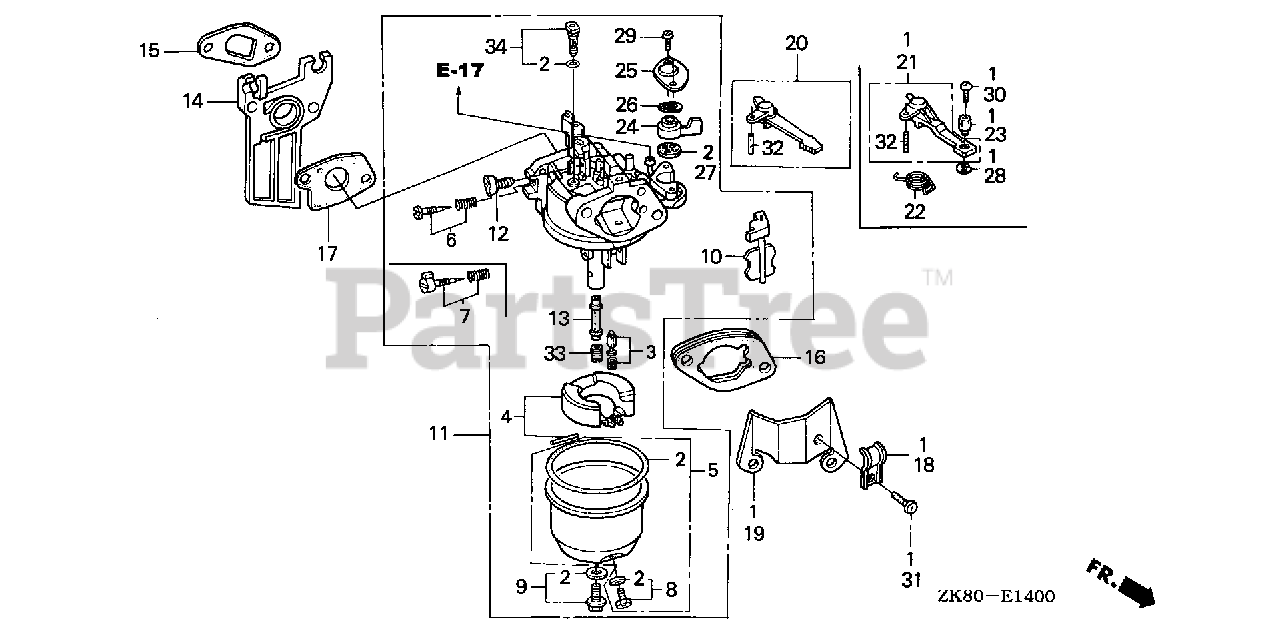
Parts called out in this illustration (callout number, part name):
1	CHOKE KIT, REMOTE CONTROL
2	GASKET SET
3	VALVE SET, FLOAT (SEAT NOT INCLUDED)
4	FLOAT SET
5	CHAMBER SET, FLOAT
6	SCREW SET, PILOT
8	SCREW SET, DRAIN
9	SCREW SET
10	CHOKE SET
11	CARBURETOR ASSY. (BE06H C)
12	SCREW, THROTTLE STOP
13	NOZZLE, MAIN
14	INSULATOR, CARBURETOR
15	GASKET, INSULATOR
16	SPACER, CARBURETOR
17	GASKET, CARBURETOR
18	HOLDER, CONTROL CABLE
19	STAY, CHOKE CONTROL
20	LEVER, CHOKE (STD)
21	LEVER, CHOKE (REMOTE)
22	SPRING, RETURN
23	HOLDER, CABLE
24	LEVER, PETCOCK
25	PLATE, LEVER SETTING
26	SPRING, PETCOCK LEVER
27	GASKET, PETCOCK
28	CIRCLIP (5MM)
29	SCREW, PAN (3X6)
30	SCREW, PAN (4X8)
31	SCREW, PAN (5X8)
32	PIN, SPRING (2X12)
33	JET, MAIN (#65)
33	JET, MAIN (#68)
33	JET, MAIN (#70)
34	JET SET, PILOT (#35)
